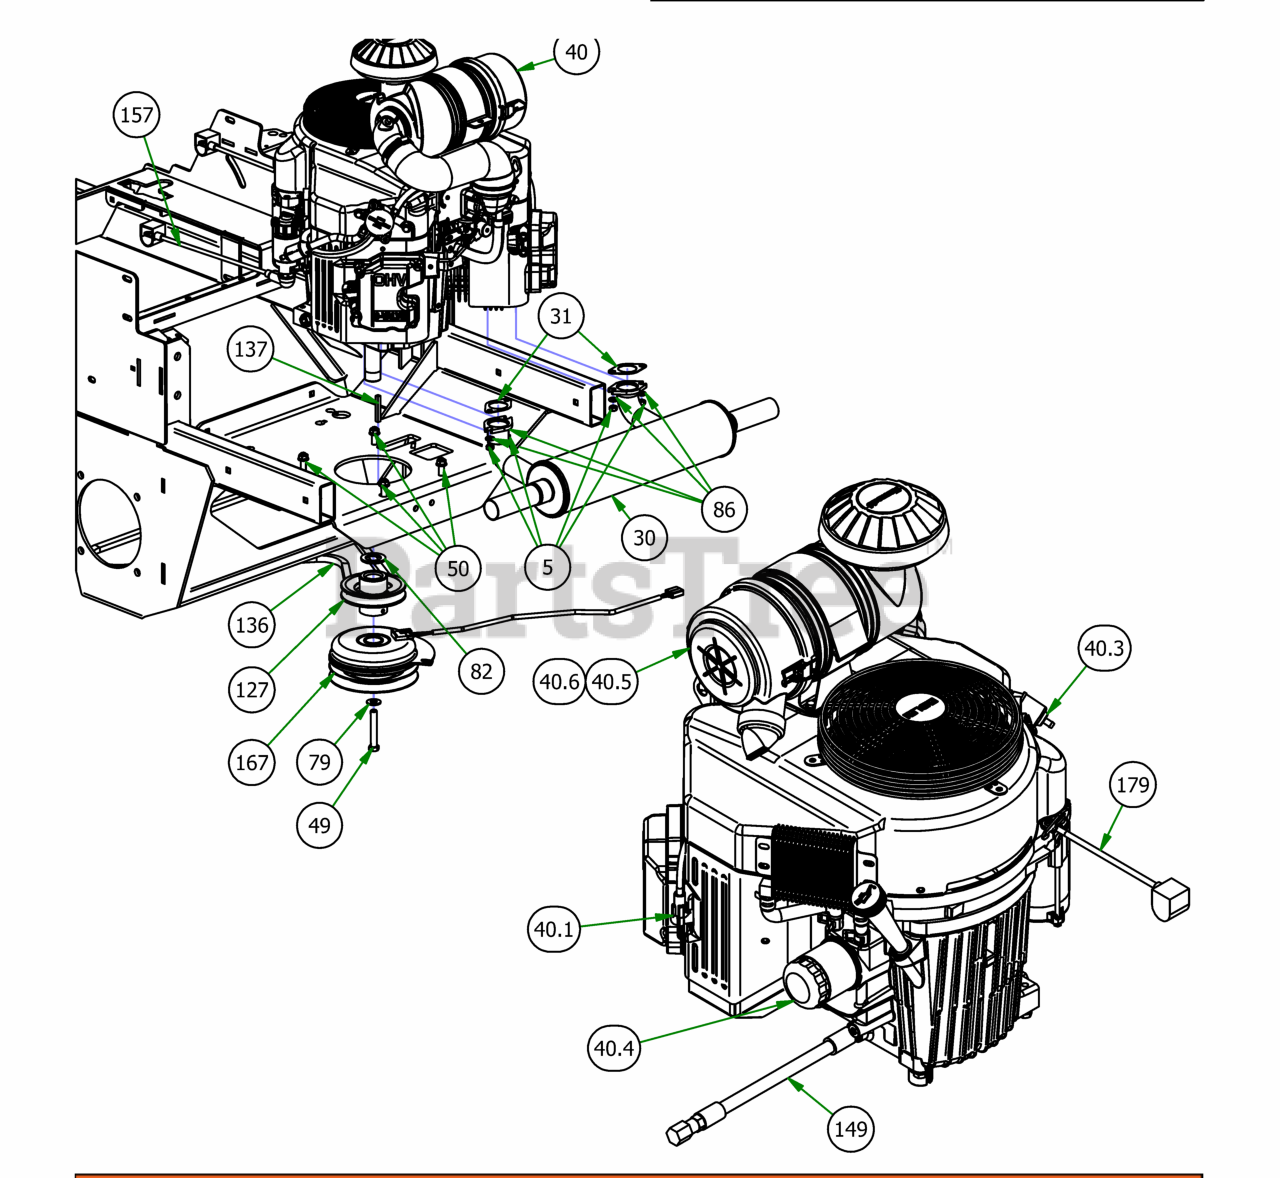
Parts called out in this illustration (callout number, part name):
5	M8-1.25 Zinc Nut
10	3/8-16 HEX SERRATED FLANGE NUT HARD/ZINC
30	Muffler for Kawasaki FX1000
31	Exhaust Gasket
40	Kawasaki FX1000 Engine
40.1	Spark Plug - Kawasaki
40.3	Universal Inline Fuel Filter
40.4	Oil Filter
40.5	Canister Air Filter- Outer
40.6	Canister Air Filter- Inner
49	7/16-20 x 2 3/4 Hex C/S GR 8 Yellow Zinc
50	3/8 x 1 1/8 bolt
72	3/8-16 X 1-1/2 HEX CAP SCREW (GR.5) ZINC
79	3/8 FLAT WASHER USS (1" OD) ZINC
82	1 1/8" Flat Spacer
86	5/16" Lock Washer
127	4 3/4 Motor Pulley
136	2019 Rebel Pump Belt
137	1/4 x 2 Square key Stock
149	Kawasaki Oil Drain
157	14" Red Battery Cable-Base Outlaw
167	Clutch Assembly
168	Clutch Pigtail
169	2019 Rebel Frame - Powdercoated
179	Starter Cable
